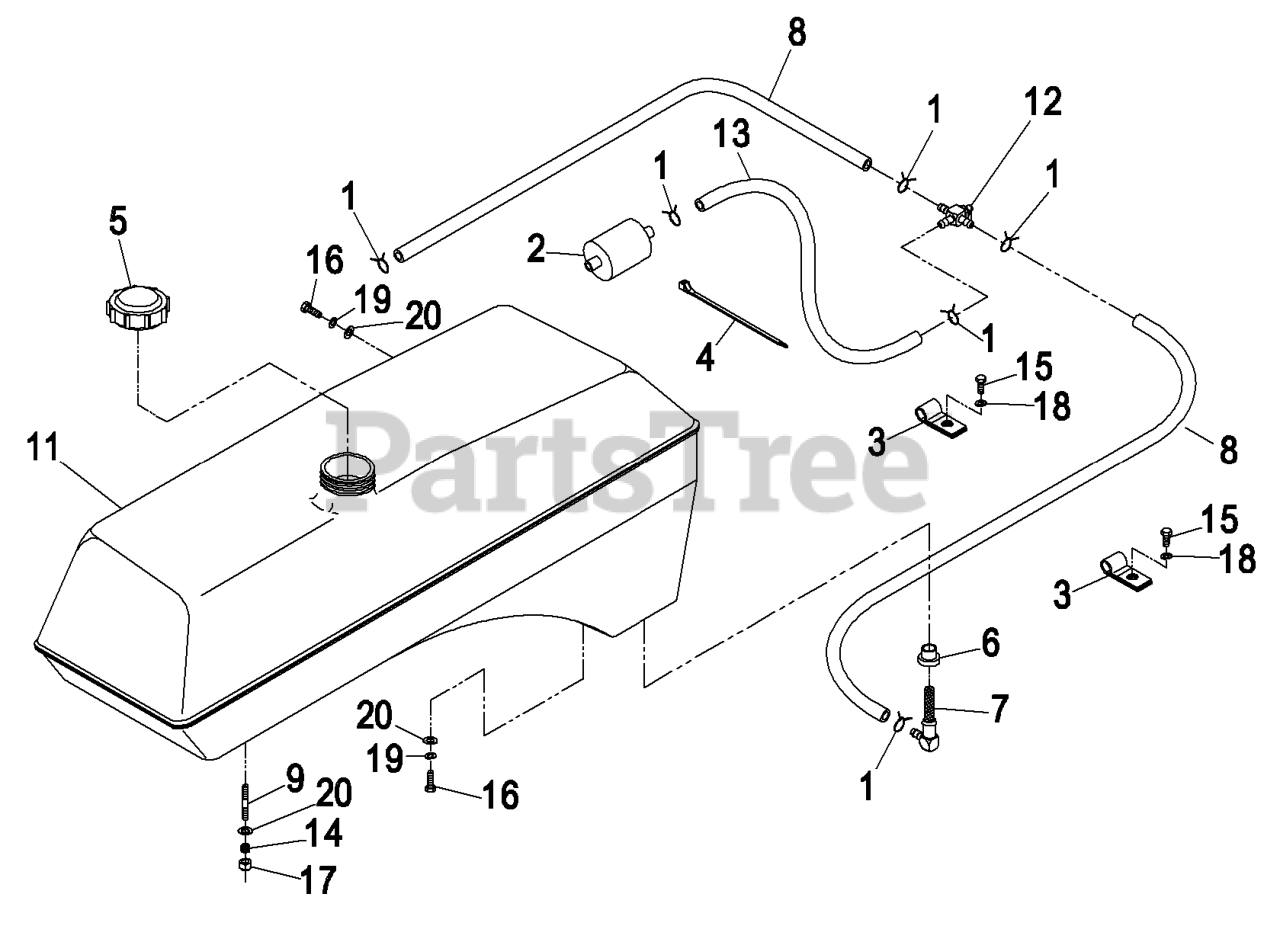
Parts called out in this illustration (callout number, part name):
1	Clamp, Fuel Line
2	Fuel Filter
3	Clip, Loom .50
4	Plastic Tie (Large)
5	Cap, Fuel Tank
6	Bushing
7	Elbow, Strainer
8	Fuel Line
9	Stud, Fuel Tank
11	Tank, Fuel (Rh)
12	Valve, Fuel
13	Fuel Line
14	Spring, Fuel Tank
15	SCREW-HH
16	SCREW-HH
17	NUT-LOCK, NI
18	Washer, Lock 1/4
19	Washer, Lock 5/16
20	WASHER-PLAIN
